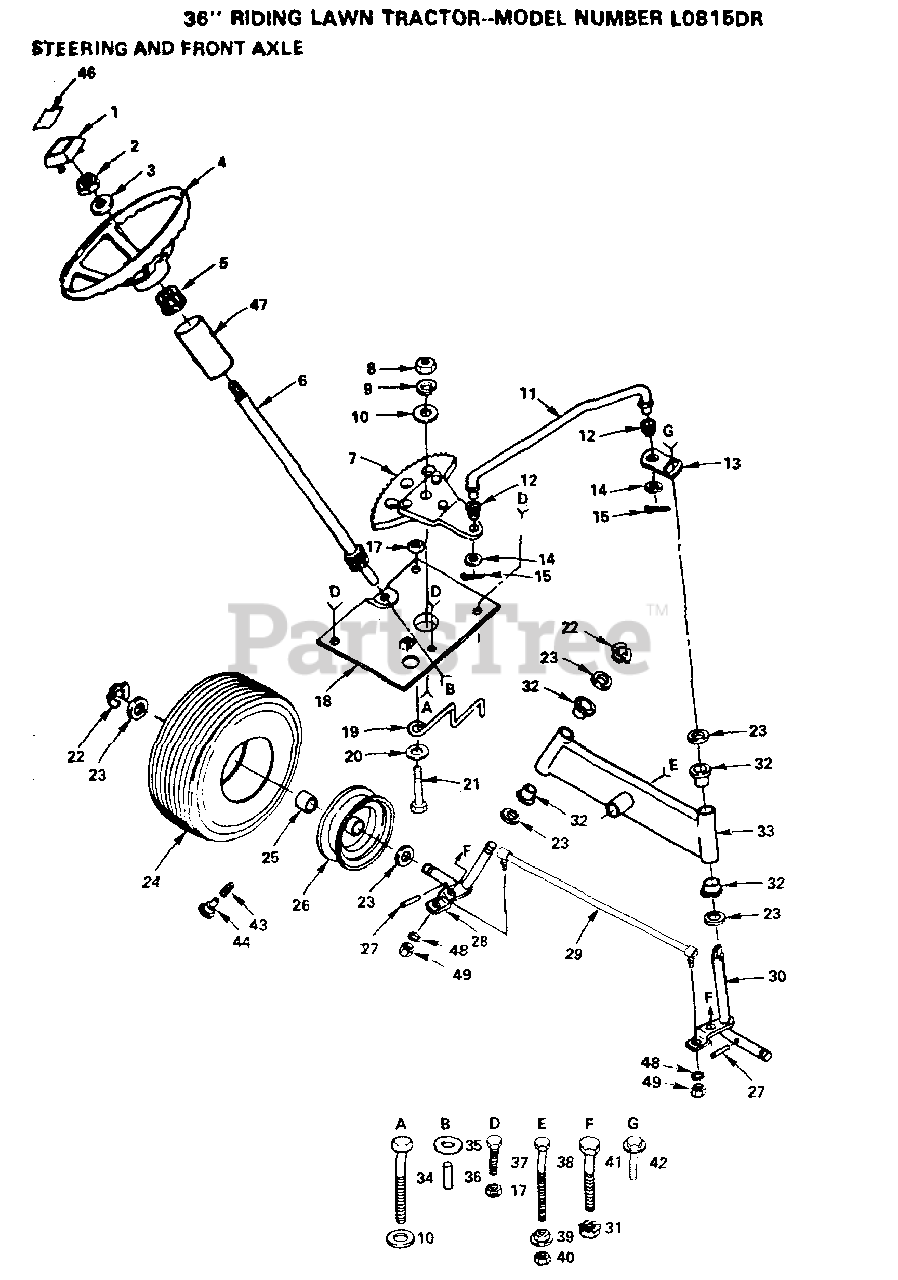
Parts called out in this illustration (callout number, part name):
1	INSERT-WHEEL LT
2	NUT
3	WASHER T
5	ADAPTER-WHEEL LT
6	STEERING ASSM T
7	STRG SECTOR LT
8	NUT
9	LOCKWASHER
10	WASHER LT
11	DRAG LINK LT
13	STEERING ARM LT
14	WASHER
15	PIN COTTER 1/8
18	SUPPORT SECTOR LT
19	BELT GUIDE LT
22	RING
25	"FLANGE, BEARING"
26	RIM ASSY LT
30	SPINDLE RH T
31	NUT
32	COL. SRTG. BEAR.
33	FRONT AXLE LT
35	WASHER
37	BOLT
38	BOLT
41	BOLT
43	VALVE CAP
44	VALVE STEM LT
48	LOCKWASHER
49	NUT
